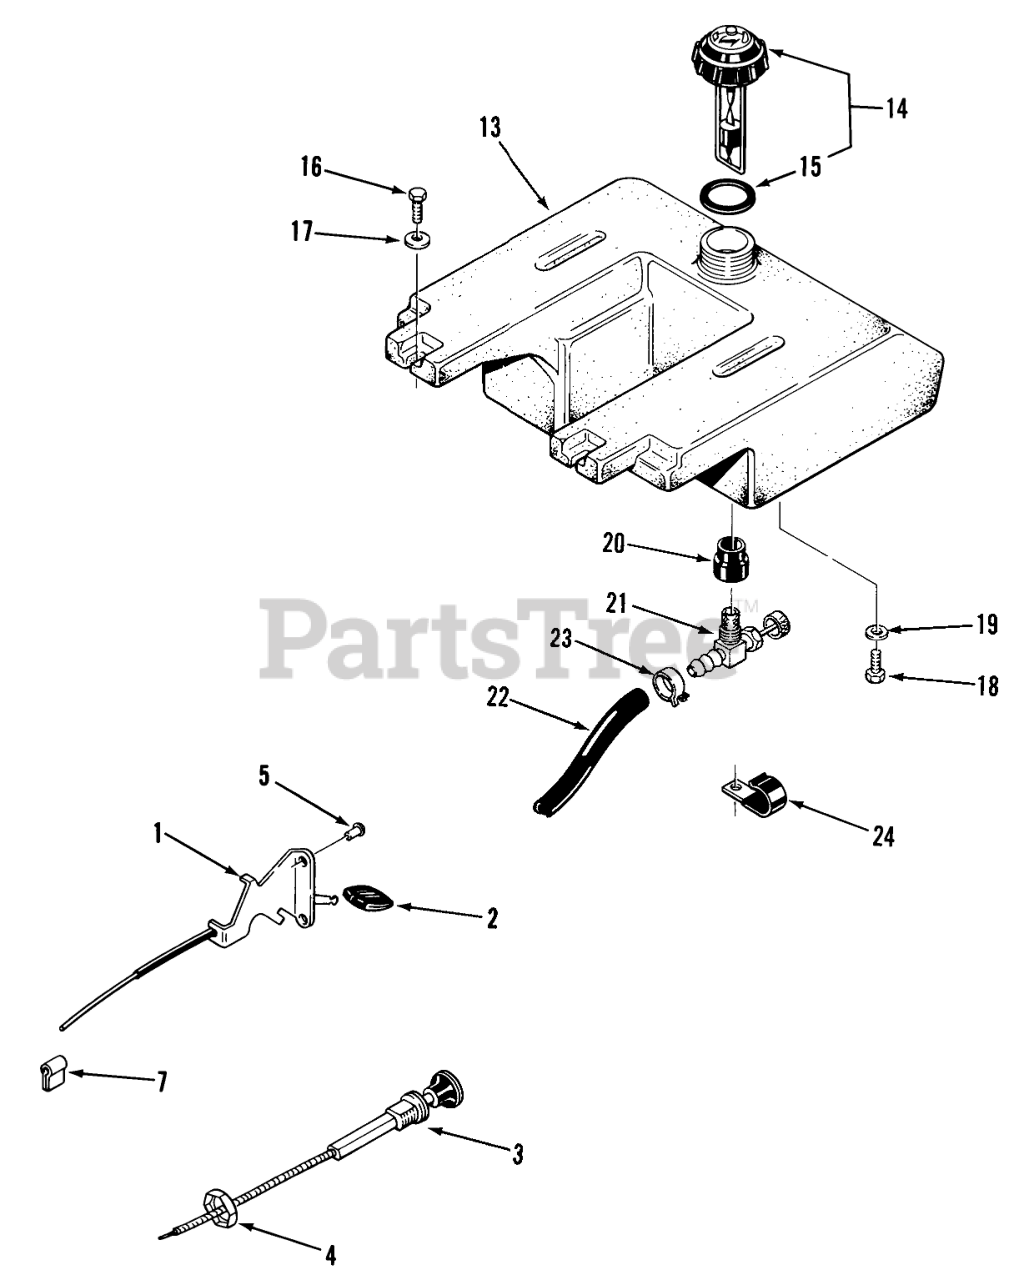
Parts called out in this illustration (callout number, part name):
1	ASSY-THROTTLE CONTRO
1	CONTROL-THROTTLE
2	KNOB-THROTTLE
3	CONTROL-CHOKE
4	NUT-HEX PALNUT
5	RIVET-4
7	THROTTLE CONTROL CLP
13	TANK-FUEL
14	ASSY-GAUGE CAP
15	GASKET-GAS CAP
16	Bolt
17	Washer
18	Bolt
19	Lockwasher
20	BUSHING
21	VALVE-FUEL
22	Fuel Line
23	Clamp
24	CLIP
